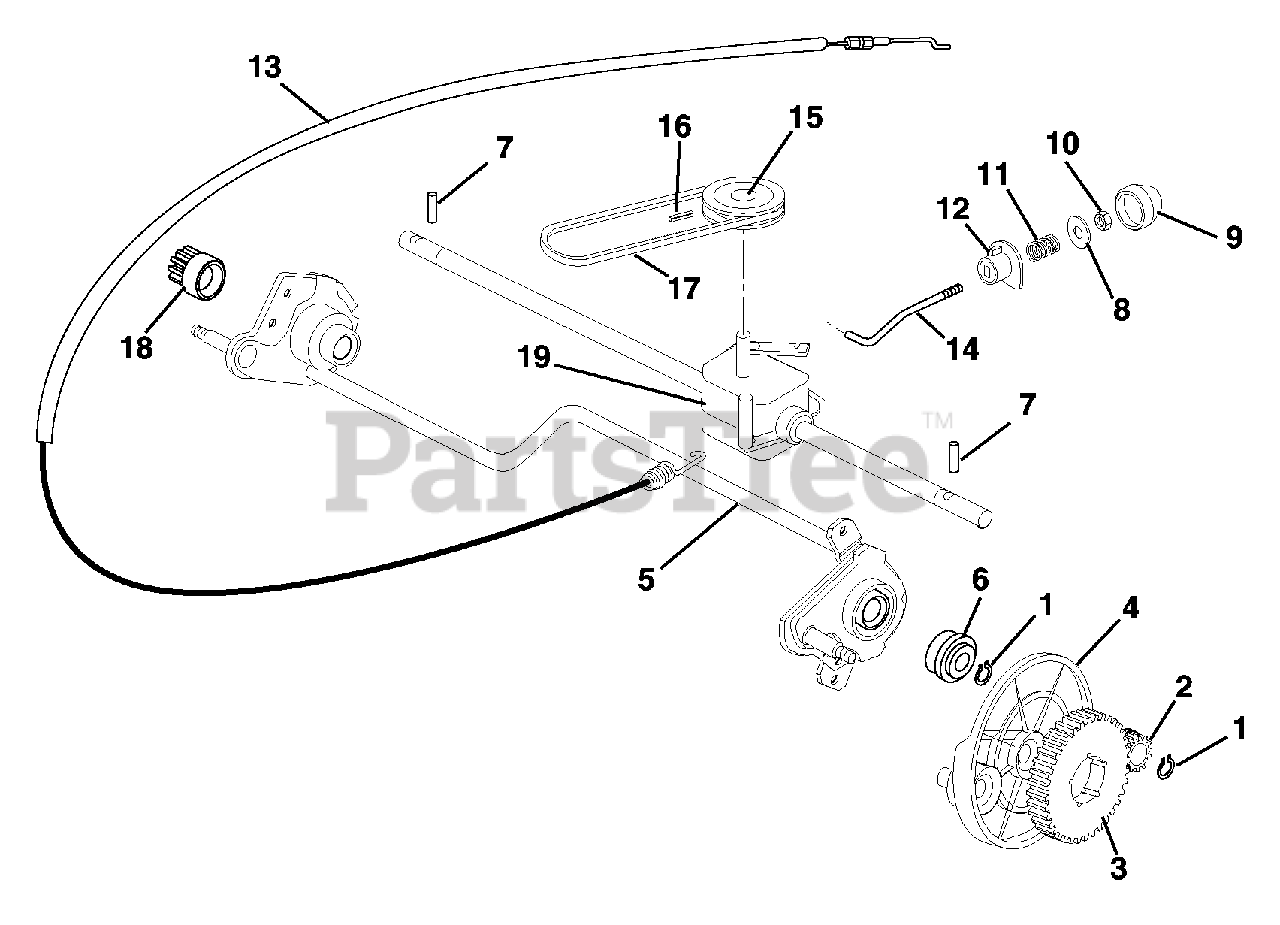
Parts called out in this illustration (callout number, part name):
1	SNAP RING
2	PINION, LEFT
3	GEAR, RING
4	PROTECTION, WHEEL
5	AXLE, REAR WHEEL
6	BEARING
12	BUSHING
13	CABLE, REAR DRIVE
14	ROD, ADJUSTMENT
15	PULLEY
16	PIN
17	BELT, Z33
18	PINION, RIGHT
19	GEAR BOX
